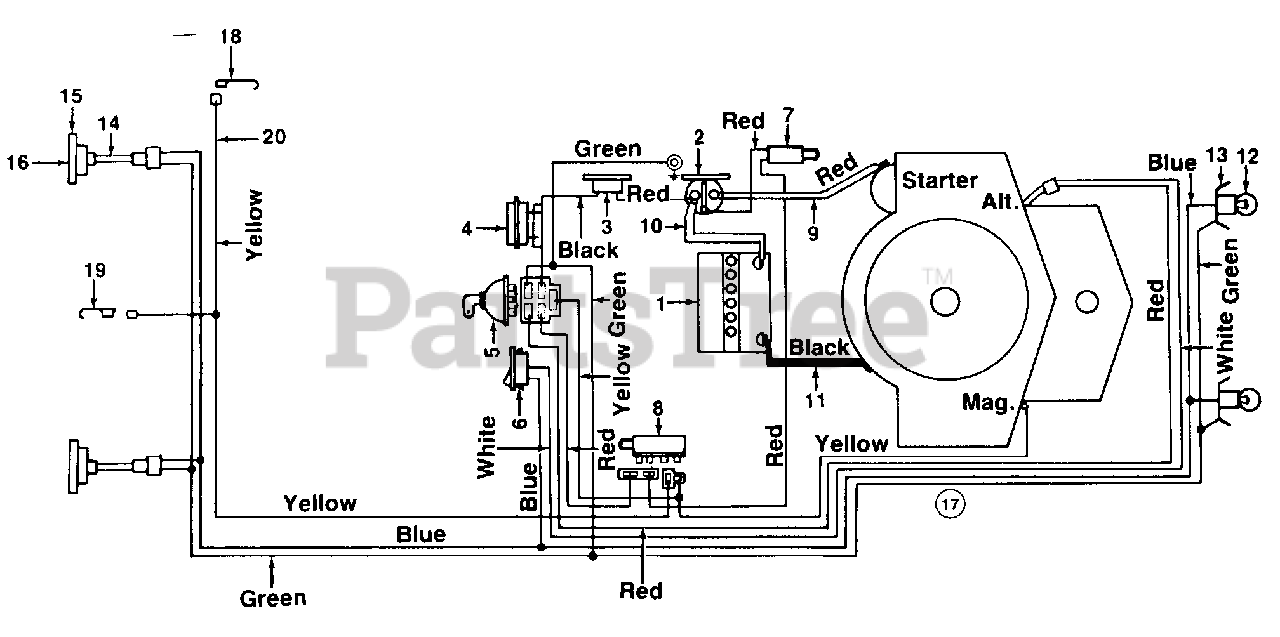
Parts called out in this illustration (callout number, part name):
1	Battery
2	Solenoid
3	Circuit Breaker
4	Ammeter
5	Ignition Switch
6	Light Switch
7	Safety Switch
8	Safety Switch
9	Electric Wire 14" Lg.
10	Electric Wire 7.5" Lg.
11	Ground Wire 7.5" Lg.
12	Lamp
13	Socket
14	Taillight Harness
15	Taillight Ass'y.
16	Taillight Bulb
17	Wire Harness
18	Spring Switch
19	Spring Switch
20	Transmission Ext. Wire
